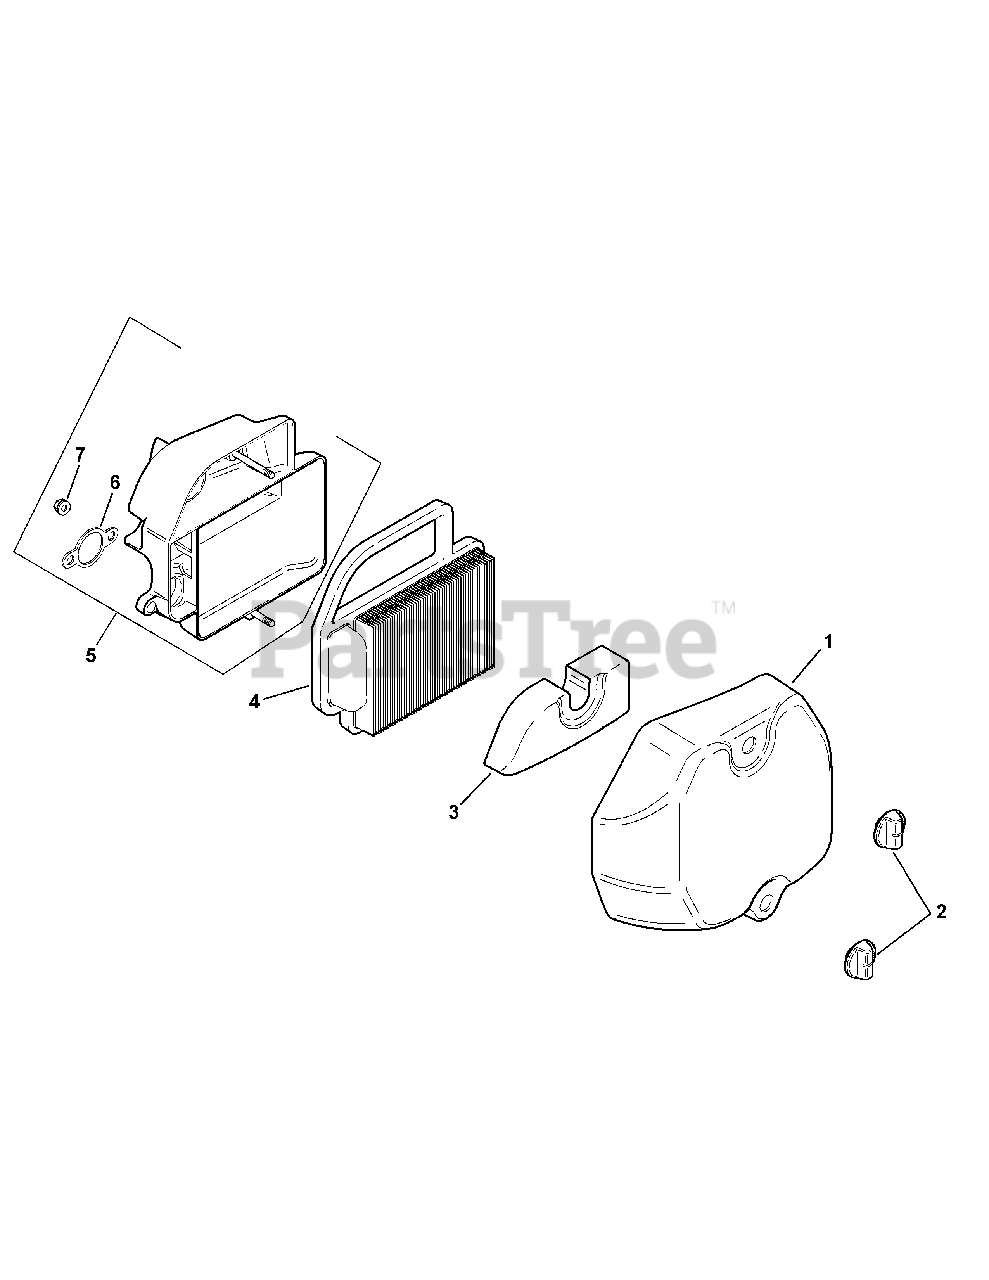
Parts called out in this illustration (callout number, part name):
1	Air Cleaner Cover
3	Pre-Cleaner Element
4	Air Cleaner Element
5	Air Cleaner Base Kit (Inc. 6 & 7)
6	Air Cleaner Base Gasket
7	Hex Flange Nut, M6 x 1.0
